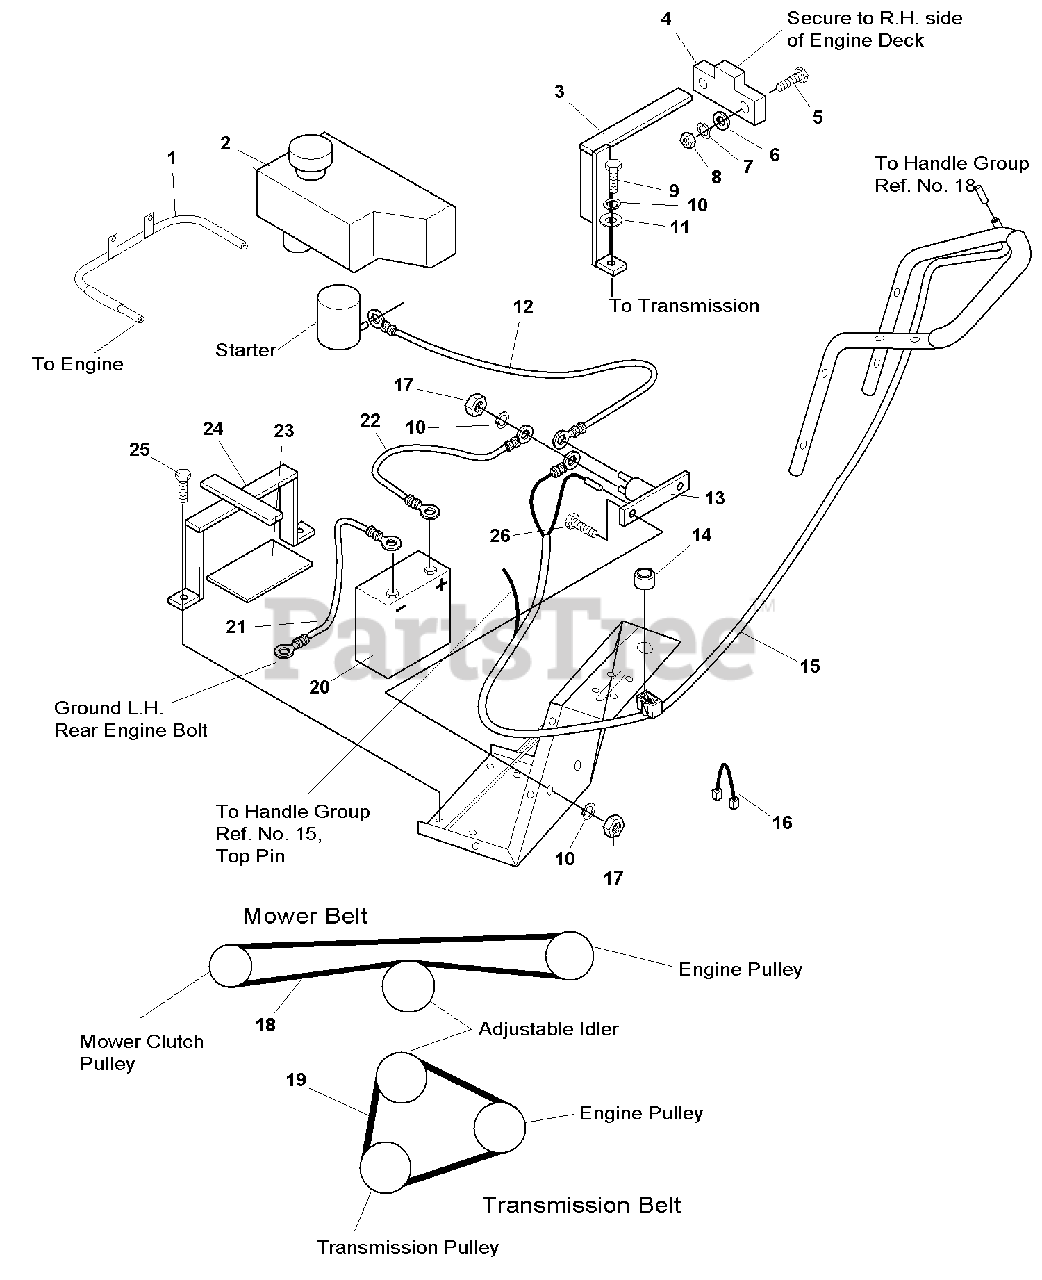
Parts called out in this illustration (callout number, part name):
1	Auxiliary Fuel Line w/Clamps - 9" - 13 HP Honda
1	Auxiliary Fuel Line w/Clamps - 18" - 15 HP Kawasaki & 13.5 Briggs & Stratton
2	Auxiliary Fuel Tank
4	Plate, Lock Engage / Disengage
5	Capscrew, 5/16-18 x 3/4
6	Flatwasher, 5/16
7	Lockwasher, 5/16
8	Nut, Hex, 5/16-28
9	Capscrew, Hex Head, 1/4-28 x 5/8
10	Washer, Plain 1/4
11	Flatwasher, 1/4
12	Cable, Solenoid to Starter Coil
13	Solenoid
14	Keyed start switch, Kit
14	SWITCH, Start Keyed
14	Keyed off switch (manual start units only)
14	Keyed off switch, Honda Models
15	Wire Harness, Honda
15	Wire Harness, Briggs & Stratton
15	Wire Harness, Kawasaki
16	Wire, Jumper, Honda Models
17	Nut, Hex, 1/4-20
18	Belt, Blade Clutch Drive
19	Belt, Transmission Drive
21	Cable, Battery Negative to Ground
22	Cable, Battery Positive to Solenoid
23	Battery Rubber
24	Battery Hold-Down
25	Capscrew, TEK, #12 x 3/4
26	Capscrew, Hex Head, 1/4-20 x 3/4
